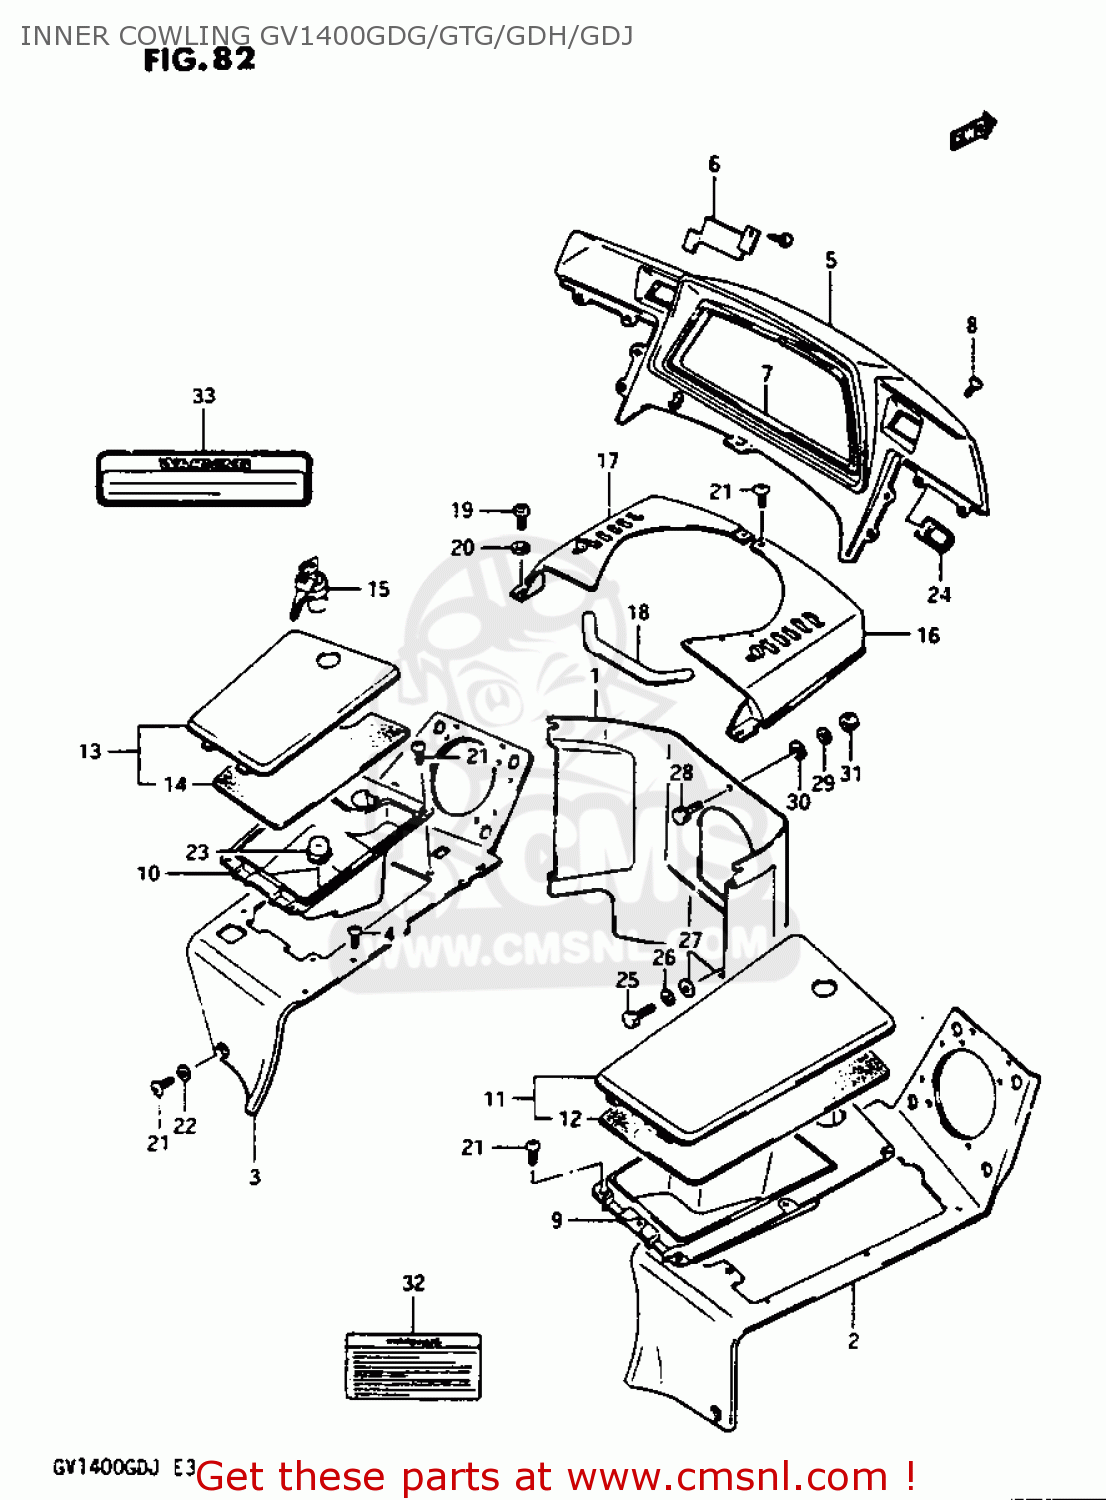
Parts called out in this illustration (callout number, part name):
1	COVER,COWLING,INNER
2	PANEL,COWLING,R
3	PANEL,COWLING,L
4	SCREW
5	COVER ASSY,METER
6	COVER,METER COVER HOLE
7	MOLDING,METER COVER
8	SCREW 5X10
9	BOX ASSY,COWLING PANEL R
10	BOX,COWLING PANEL,LEFT
11	LID,COWLING BOX RH
12	SEAL,LID,RIGHT
13	LID,COWLING BOX LH
14	SEAL,LID,LEFT
15	LOCK SET,TOOL HOLDER
16	COVER ASSY,FRAME HEAD,R(BLACK)
17	COVER ASSY,FRAME HEAD,L(BLACK)
18	SEAL,FRAME HEAD
19	SCREW
20	WASHER,5.5X12X
21	SCREW
22	WASHER (4.3X13X0.80)
23	CAP(OD:30)
24	CAP,RADIO IND
25	BOLT
26	LOCK WASHER
27	WASHER,5.5X12X
28	BOLT
29	LOCK WASHER
30	WASHER,5.5X12X
31	NUT
32	LABEL (WARNING)
33	LABEL (WARNING COVER CO
